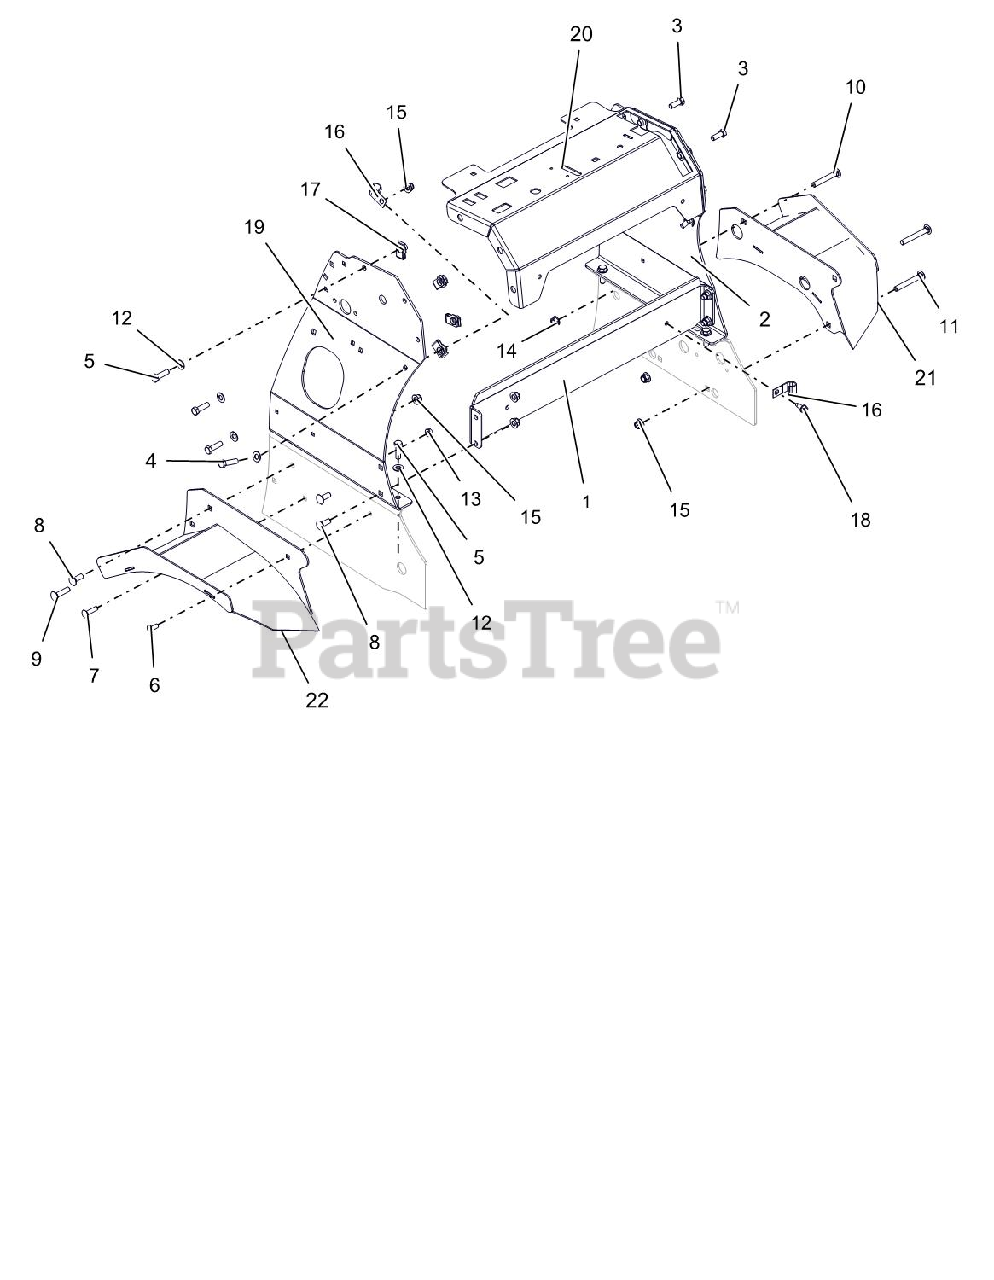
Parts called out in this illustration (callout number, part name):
1	STIFFENER, TOWER
2	PANEL, LH TOWER SIDE
3	@BLT-HEX .38-16X1.00 GR5 YWZC
4	@BLT-HEX .38-16X1.50 GR5 YWZC
5	@BLT-HEX .38-16X1.25 GR5 YWZC
6	@BLT-RDHDSQNK .31-18X.75 G5YZ
7	@BLT-RDHDSQNK .31-18X1.25 G5YZ
8	@BLT-RDHDSQNK .38-16X1.00 G5YZ
9	@BLT-RDHDSQNK .38-16X1.50 G5YZ
10	@BLT-RDHDSQNK .38-16X2.50 G5YZ
11	@BLT-RDHDSQNK .38-16X2.75 G5YZ
12	@WSHR-FL-STL.406X.812X.065 YWZ
13	@NUT-SPNLK-FLG .312-18 YWZC
14	@NUT-LK-TOP-FLG .38-16 YWZC
15	@NUT-LK-NYL-FLG .38-16 YWZC
17	NUT-RTNR .375-16X.37
18	@SCR-TAP .31-18X.75 HWH TR YWZ
19	KIT, SERVICE RH TOWER
20	KIT, DASH WITH EFI DECAL
21	WLDMT, LH FENDER
22	WLDMT, RH FENDER
